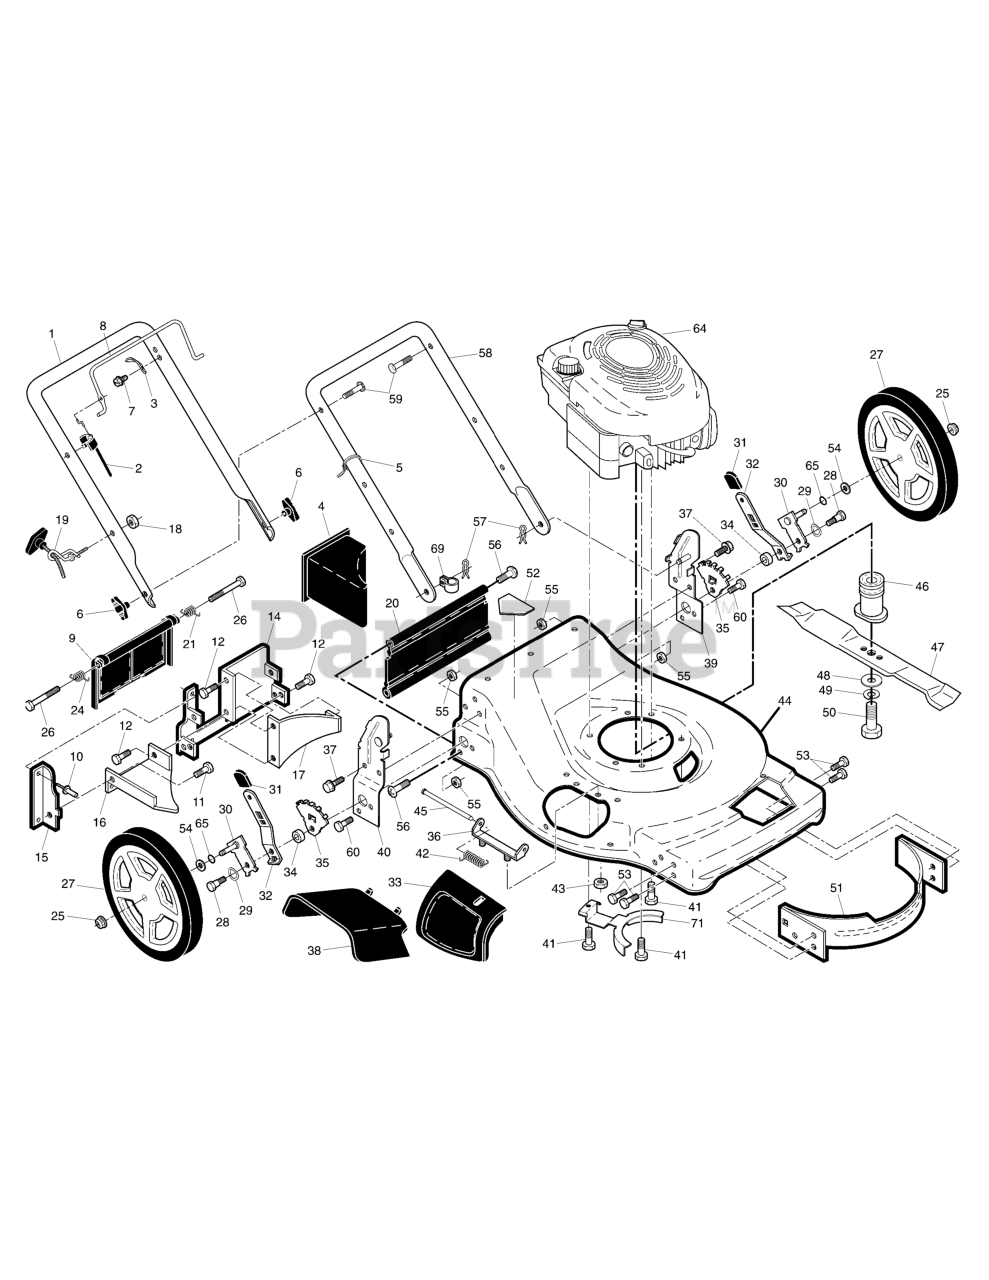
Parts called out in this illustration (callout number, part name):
1	Upper Handle
2	Engine Zone Control Cable
3	Bracket, Upstop
4	Mulcher Plug
5	Wire Tie
6	Handle Knob
8	Control Bar
9	Rear Door Assembly
10	Pop Rivet
11	Screw, Self-Tapping, #10-24 X 5/8
12	Screw, Sems, Hex Head, 1/4-20 X 1/2
14	Back Plate
15	Side Baffle
16	Discharge Baffle
17	Rear Baffle
18	Keps Locknut 1/4-20
19	Rope Guide
20	Rear Skirt
21	Spring, Rear Door, LH
24	Spring, Rear Door, RH
25	** Nut, Hex, Flanged
26	Bolt, Rear Door
27	Wheel & Tire Assy., Rear
28	Bolt, Shoulder 3/8-16 x 1
29	Washer, Curved, Cylindrical
30	Axle Arm Assembly
31	Selector Knob
32	Selector Spring
33	Mulcher Door
34	Spacer
35	Wheel Adjusting Bracket, RH
36	Hinge Bracket
37	Screw
38	Discharge Defl ector
39	Handle Bracket Assy., LH
40	Handle Bracket Assy., RH
41	Screw, Hex Head, Thread Roll, 3/8-16 x 1-1/8
42	Hinge Spring
43	Nut, Hex, Nylock
44	Kit, Housing (Includes Ref. Nos. 14, 15 & 51)
45	Hinge Rod
46	Blade Adapter / Pulley
47	Blade, 22"
48	Washer, Hardened
49	Washer, Helical
50	Screw, Machine, Hex Head, 3/8-24 x 1-3/8, G8
51	Kit, Front Baffle (Includes Ref. 53)
52	Danger Decal
53	Screw, Serrated, Type TT, 1/4-20
54	Washer, Flat
55	Nut, Hex 3/8-16
56	Hinge Screw 1/4-20 x 1-1/4
57	Hairpin Cotter
58	Lower Handle
59	Handle Bolt
60	Bolt, Hex Head 3/8-16 x 3/4
64	* Engine, Briggs & Stratton
65	O-RING
69	Clip, Cable
71	Belt Keeper
